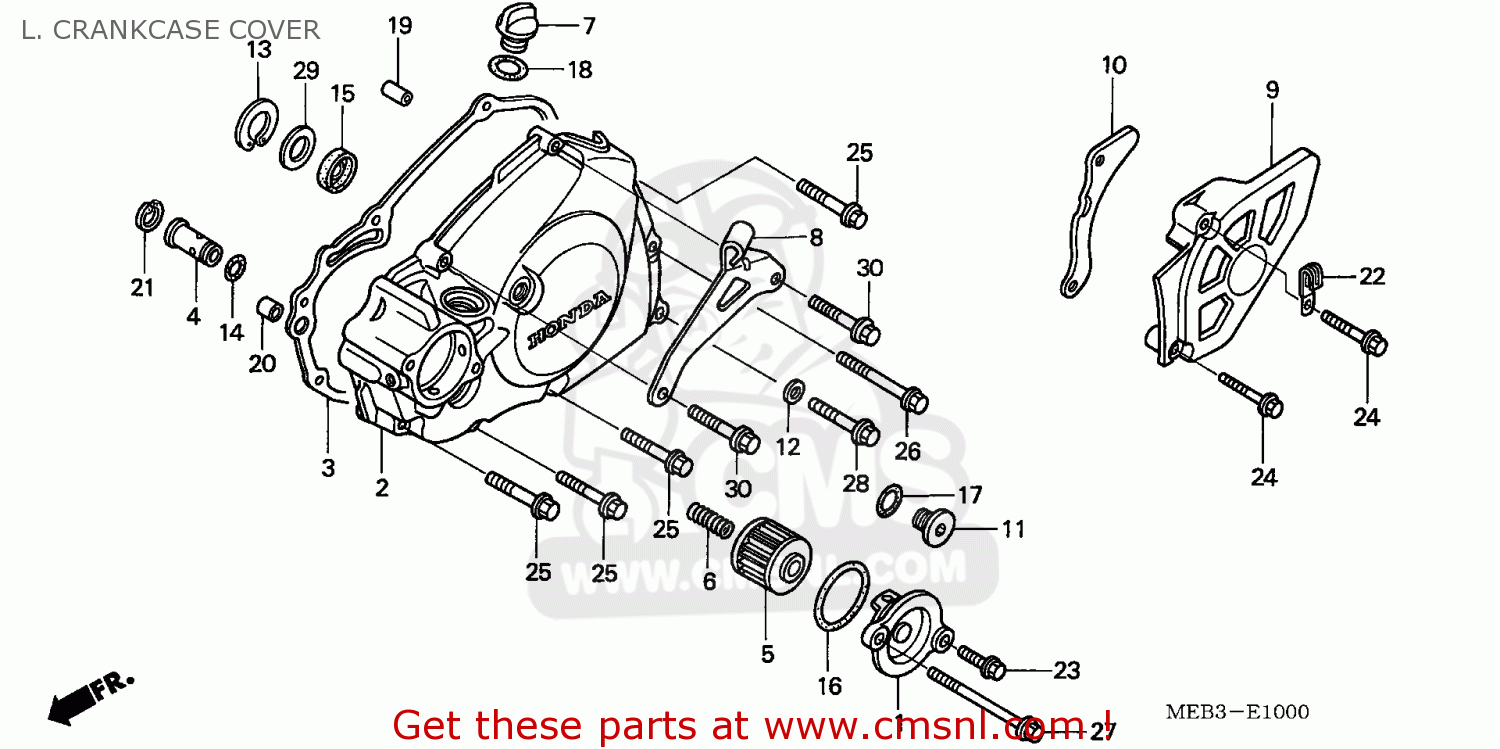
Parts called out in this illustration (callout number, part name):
1	COVER,OIL FILTER
2	COVER COMP,L CRAN
3	GASKET,L COVER (NAS)
4	VALVE ASSY,RELIEF
5	FILTER COMP,ENGIN
6	SPG,OIL FILTER
7	CAP,OIL FILLER
8	RECEIVER,CLUTCH C
9	COVER COMP,DRIVE
10	GUIDE,DRIVE CHAIN
11	CAP,14MM
12	WASHER,8MM
13	CIRCLIP,IN 24MM S
14	O RING 8.5X1.7
15	OIL SEAL,10X21X5
16	O-RING, 39.8X2.2
17	O-RING,13.8X2.5
18	ORING 183
21	CIRCLIP IN 14MM
22	CLIP,4X50
23	BOLT,FLANGE,SH,6X16
24	BOLT,FLANGE SH 6X
25	BOLT,FLANGE,6X32
26	BOLT,FLANGE,SH,6X40
27	BOLT,FLANGE,6X75
28	BOLT,FLANGE,DR,8X
29	WASH,THRUST 13MM
30	BOLT,FLANGE,6X32
